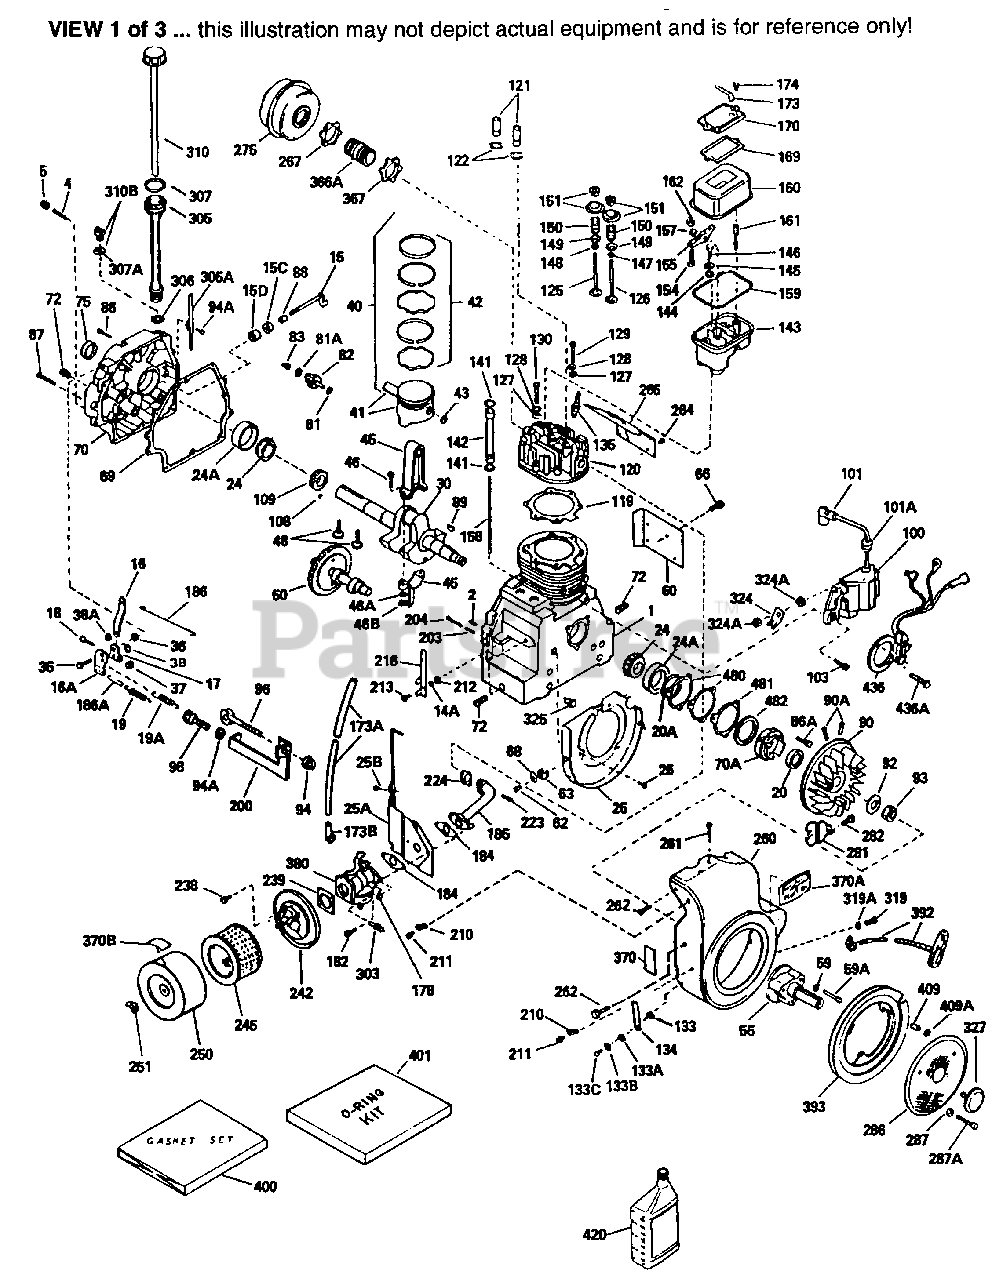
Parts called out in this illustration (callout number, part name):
1	"Cylinder (Incl. 2, 72, 75, & 80)
2	Dowel Pin
3	Screw, 5/16-18 x 1/2"
15	Governor Rod
16	Governor Lever
16B	Governor Spring Plate
17	Governor Lever Clamp
18	Screw, Torx T-25, 10-24 x 7/8"
19	Extension Spring
19A	Control Spring
20A	"O" Ring
24	Tapered Bearing
24A	Bearing Cup
25	Blower Housing Baffle
25A	Air Baffle
25B	Screw, 1/4-20 x 1"
26	Screw, 1/4-20 x 5/8"
30	Crankshaft
35	Screw, 10-32 x 1/2"
37	Lock Nut, 10-24
40	Piston, Pin & Ring Set (Std.)
40	Piston, Pin & Ring Set (.010" OS)
40	Piston, Pin & Ring Set (.020" OS)
40	Piston, Pin & Ring Set (.040" OS)
40	Piston, Pin & Ring Set (.030" OS)
41	Piston & Pin Ass'y. (Std.) (Incl. 43)
41	Piston & Pin Ass'y. (.010" OS) Incl. 43
41	Piston & Pin Ass'y. (.020" OS) Incl. 43
41	Piston & Pin Ass'y. (.030" OS) Incl. 43
41	Piston & Pin Ass'y. (.040" OS) Incl. 43
42	Ring Set (Std.)
42	Ring Set (.010" OS)
42	Ring Set (.020" OS)
42	Ring Set (.030" OS)
42	Ring Set (.040" OS)
43	Piston Pin Retaining Ring
45	Connecting Rod Ass'y. (Std.) Incl. 46 -46B
45	Connecting Rod Ass'y. (.010" US) Incl . 46-46B
45	Connecting Rod Ass'y. (.020" US) Incl . 46-46B
46	Connecting Rod Bolt
48	Valve Lifter
50	Camshaft (MCR)
60	Blower Housing Extension
62	Screw, 8-32 x 3/8"
65	Screw, 10-24 x 1/2"
68	Ground Terminal
69	* Cylinder Cover Gasket
70	Cylinder Cover (Incl.15,72,75,84,88)
70A	Cylinder Cover (See Ref. # 480 - 482)
72	Oil Drain Plug
72A	Oil Drain Plug
75	Oil Seal
80	Governor Shaft
82	Governor Gear Ass'y. (Incl. 81)
83	Governor Spool
84	Retaining Ring
86	Screw, 1/4-20 x 2"
86A	Screw, 5/16-18 x 7/8"
87	Screw, 1/4-20 x 1"
89	Flywheel Key
90	Flywheel (Incl. 90A)
90A	Trigger Pin Kit
92	Lock Washer
93	Flywheel Nut
100	Solid State Ignition
101	Spark Plug Cover
103	Screw, 1/4-20 x 3/4"
108	Pin, Crankshaft gear
109	Crankshaft Gear
119	* Cylinder Head Gasket
120	Cylinder Head
125	Exhaust Valve (Std.)
125	Exhaust Valve (1/32" OS)
126	Intake Valve (Std.)
126	Intake Valve (1/32" OS)
128	Belleville Washer
129	Screw, 5/16-18 x 1-5/8"
130	Screw, 5/16-18 x 1-5/8"
135	Resistor Spark Plug - RJ17LM
149	Valve Spring Cap
149A	Valve Spring Cap (1/32" OS Stem)
149C	Valve Pin
150	Valve Spring
169	* Valve Cover Gasket
170	Breather Body
173	Breather Tube
174	Screw, 10-24 x 1/2"
183	Choke Bracket
184	* Carburetor To Intake Pipe Gasket
186	Governor Link
204	Screw, 10-24 x 2"
210	Conduit Clip
211	Screw, 10-32 x 3/8"
212	Bushing
213	Screw, 10-24 x 5/8"
216	R.P.M. Adjusting Lever
238	Screw, 10-32 x 5/8"
239	* Air Cleaner Gasket
242	Air Cleaner Bracket
242A	Air Cleaner Bracket
245	Air Filter
250	Air Cleaner Cover
251	Wing Nut, 1/4-20
260	Blower Housing
261	Screw, 5/16-18 x 5/8"
264	Screw, 10-24 x 1/2"
265	Cylinder Head Cover
275	Muffler
286	Starter Screen
287	Screw, 1/4-20 x 1-1/2"
298A	Lock Nut, 1/4-20
298B	Screw, 5/16-18 x 5/8"
298C	Washer
305	Oil Fill Tube
307	"O" Ring
310	Dipstick
319	Screw, 5/16-24 x 3/8"
319	Screw, 1/4-20 x 1/2"
319A	Lock Washer
355	Starter Handle
366A	Muffler Nipple
370	Instruction Decal
370A	Decal - XL/C Industrial/Commercial
370B	Decal - Important Lubrication - SAE 3
380	Carburetor (Incl. 184)
392	Starter Rope
393	Starter Pulley
400	* Gasket Set (Incl. items marked PK in notes) Incl. part #'s 27272A (2), 296 73 (1), 31923 (1), 31956B (1), 31958A (1), 31960A (3), 31971 (2), 31972 (1 ), 32000B (1), 32246B (1), 33263 (2)
409A	Lockwasher
420	SAE 30 4-Cycle Engine Oil (Quart)
480	* Shim Gasket (.004/.005) See Repair M anual
481	* Shim Gasket (.005/.007) See Repair M anual
482	Steel Spacer (.010) See Repair Manua l
